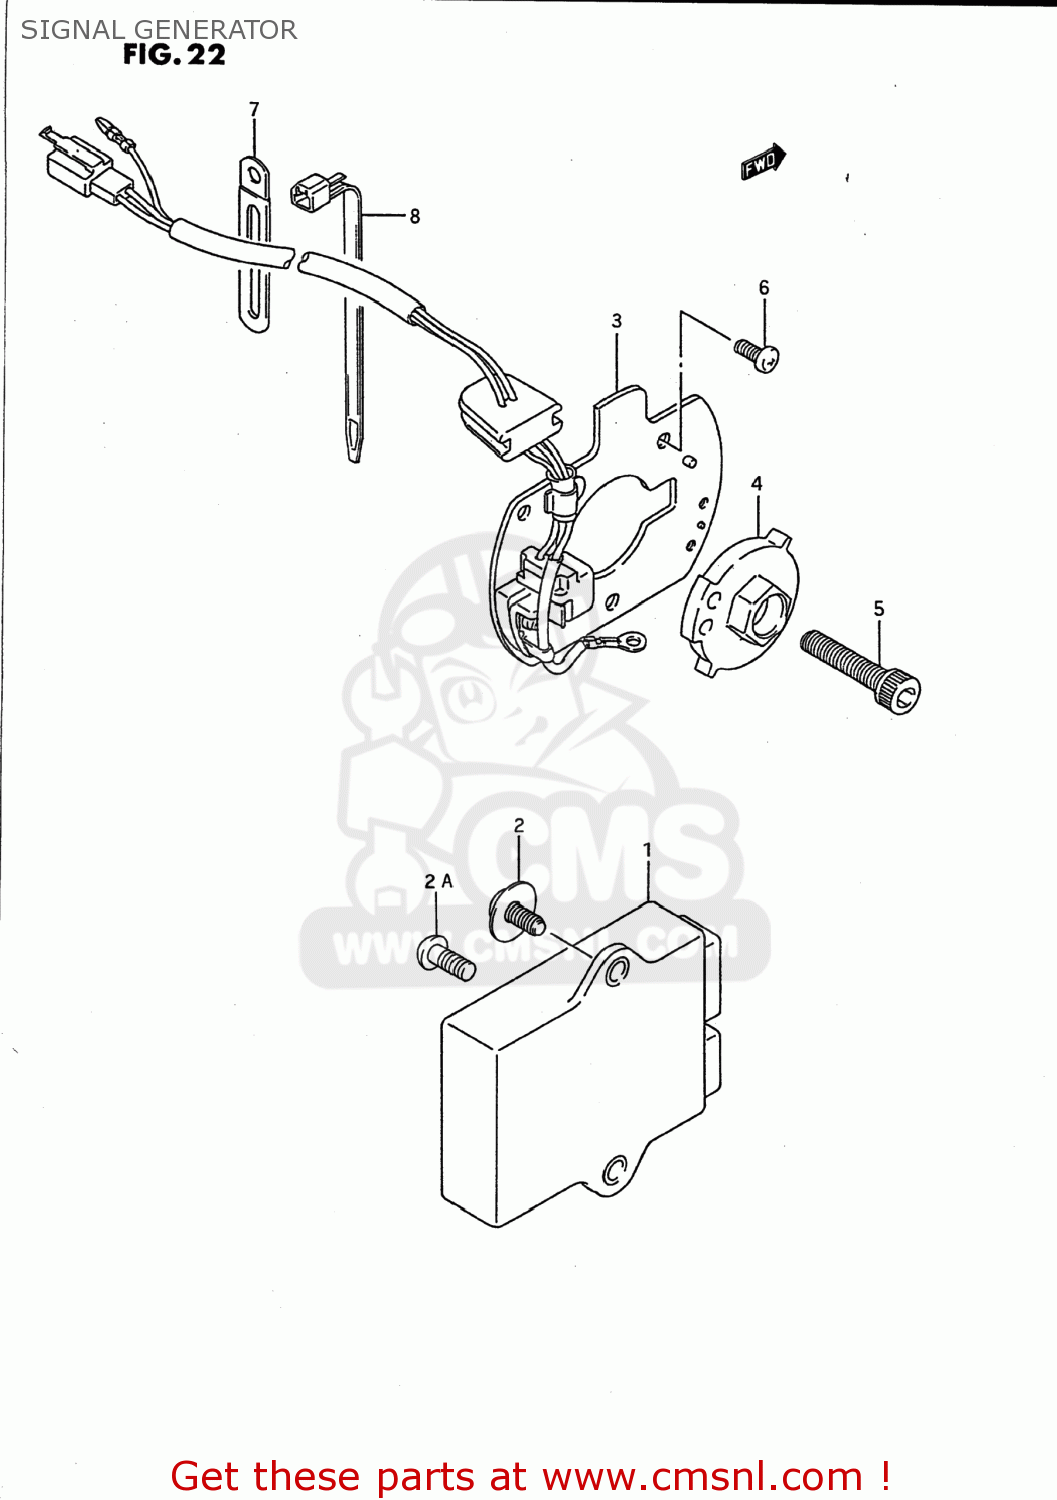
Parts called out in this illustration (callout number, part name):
1	IGNITER
2	SCREW
2A	SCREW 6X12
3	GENERATOR ASSY,SIGNAL
4	ROTOR,SIGNAL
5	BOLT
6	SCREW
7	CLAMP
8	CLAMP(L:95)
